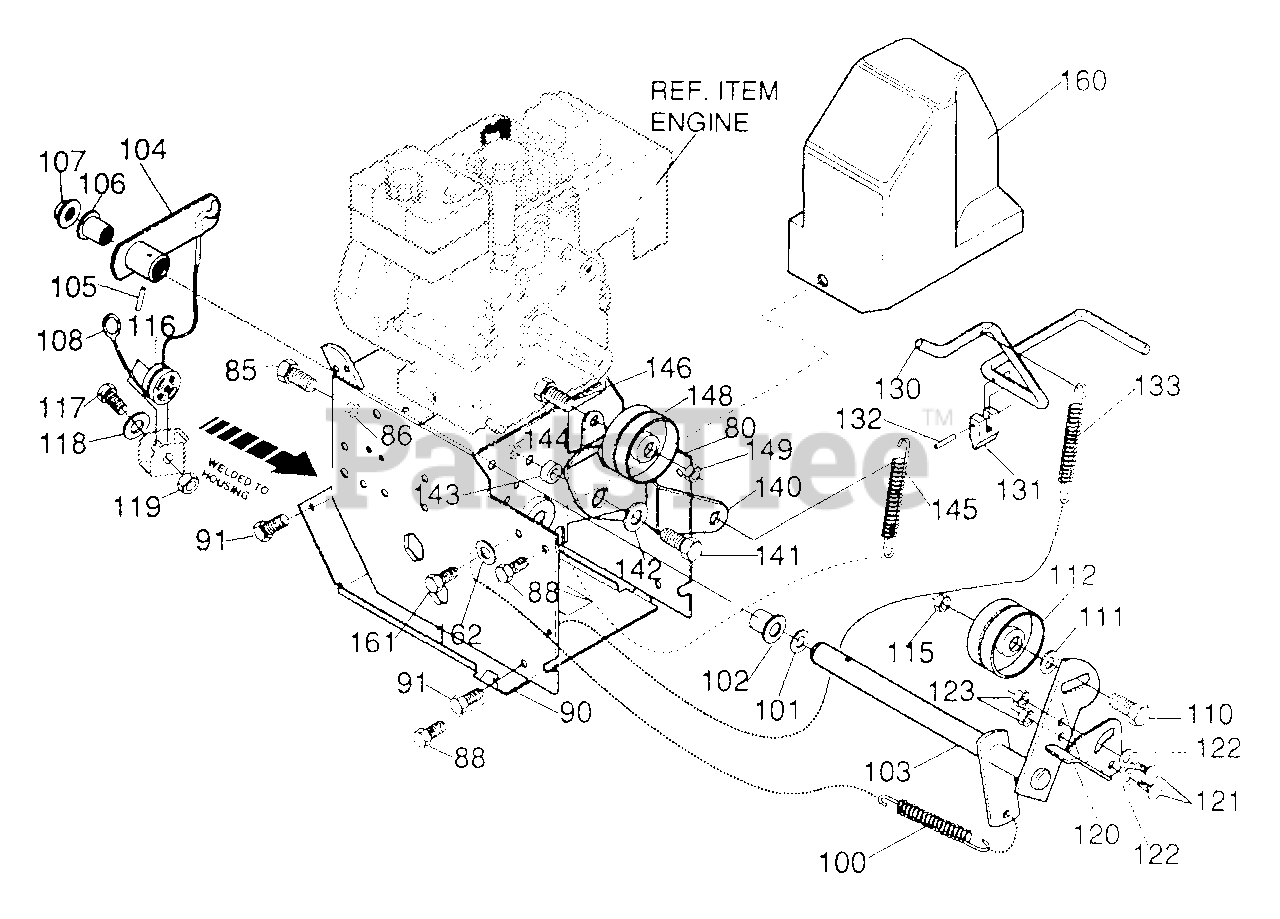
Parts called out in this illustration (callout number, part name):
80	FRAME, ASSY ENGINE MT 13"
85	SCREW, 5/16-241.00 HHC
86	NUT, 5/16-24 HEXWDFLLK
88	SCREW, 5/16-18 x .75 WAHHTAP
90	COVER, BOTTOM WHEEL DR
91	SCREW, 1/4-20 x .63 WAHHTAP
100	IDLER SPRING
101	FLATWASHER, .53 x 1.00 x .063
102	BEARING, FLANGE
103	ASSY, SHAFT AUG CLUTCH
104	LEVER, ASSY AUGER CLUTCH CABLE
105	PIN, SPRING. 165 DIA x .88LG HD
106	BEARING, FLANGE
107	NUT, 1/2 PUSHON
108	CABLE, .205 EYE 6.125 LG
110	SCREW, 3/8-16 x 1.25
111	FLATWASHER, .406 x .81 x .065
112	PULLEY, IDLER
115	NUT, 3/8-16 HXCTRLKJAM
116	SPOOL, CABLE AUGER CLUTCH
117	SCREW, 1/4-20 x 1.75
118	FLATWASHER, .281 x .63 x .065
119	NUT, 1/4-20 REGHEXCTRLK
120	CAM, BRAKE ARM
121	CARRIAGE BOLT, 1 /4-20 x .63
122	FLATWASHER, .344 x .69 x .065
123	NUT, 1/4-20 REGHEXCTRLK
131	PAD, AUGER/IMPELLER BRAKE
132	PIN, SPRING.165 DIA x .88 LONG HD
133	SPRING, TENSION RETURN
140	LEVER, IDLER ARM TRACTION
141	SCREW, 5/16-18 x .75
142	FLATWASHER,.328 x 1.38 x .075
143	BUSHING, IDLER LEVER
144	NUT, 5/16-18 HEXNYL
145	SPRING, IDLER TRACTION DRIVE
146	SCREW, 3/8-160.25 HHC
148	PULLEY, IDLER BFF 1.88 x .75
149	NUT, 3/8-16 HEXCTRLKJAM
160	COVER, BELT
161	SCREW, 1 /4-20 x .50 WAHHTAP
162	FLATWASHER, .281 x .63 x .065
